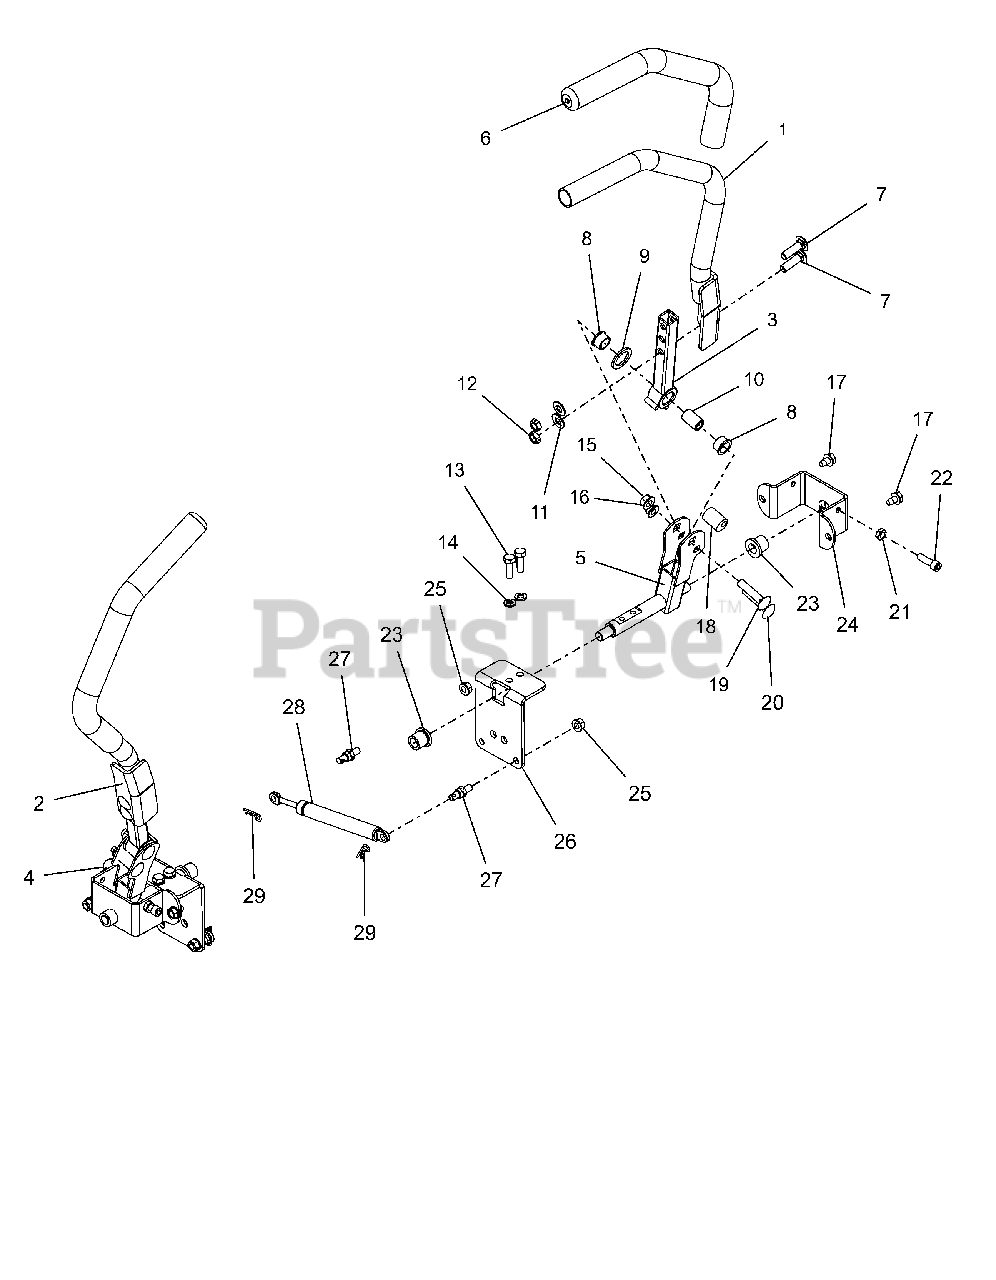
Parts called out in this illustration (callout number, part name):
1	WLDMT, STEERING HANDLE LH
2	WLDMT, STEERING HANDLE RH
3	WLDMT, UPPER CONTROL ARM
4	WLDMT,STEERING ARM LOWER RIGHT
5	WLDMT,STEERING ARM LOWER LEFT
6	GRIP, HANDLEBAR 15" FOAM
7	BLT,RHSSN-.375X1.25 G5 RIE5230
8	BSHG-FLG, .625X.75X.450X.875
9	WASHER, FRICTION .875X1.25X.10
10	SPACER, .375X.625X.970 (PM)
11	WSHR,FLT .406X.812X.065 ZCC
12	@NUT-LK-CTR-JAM .375-16 YWZC
13	BLT, HEX .31-18X1.00 G8 ZCC
14	WSHR,LK-REG .312X.078 ZCC
15	NUT-LK-CTR-FLG .375-16 GF ZCC
16	NUT,NYL-FLG .31-18 GF ZCC
17	SCR,TAP .312-18X.50 HWH TR ZCC
18	BSHG,ECCEN .328X.750X1.01 PM
19	BLT,RHSSN-.375X1.75 G5 RIE5230
20	BLT,RHSSN-.312X1.75 G5 RIE5230
21	NUT-JAM .312-18 G2 ZCC
22	SCR, SKH .312-18X1.00 G8 ZC120
23	BSHG-FLG .515X.750X.745X1.00NY
24	BRKT, STEERING
25	NUT-LK-TOP-FLG .312-18 GF ZCC
26	BRKT, STEEERING
27	COUPLER, DAMPER MOUNT
28	DAMPER, STRAIGHT MOUNT
29	PIN, HAIR #213 .08X1.19 ZCC
